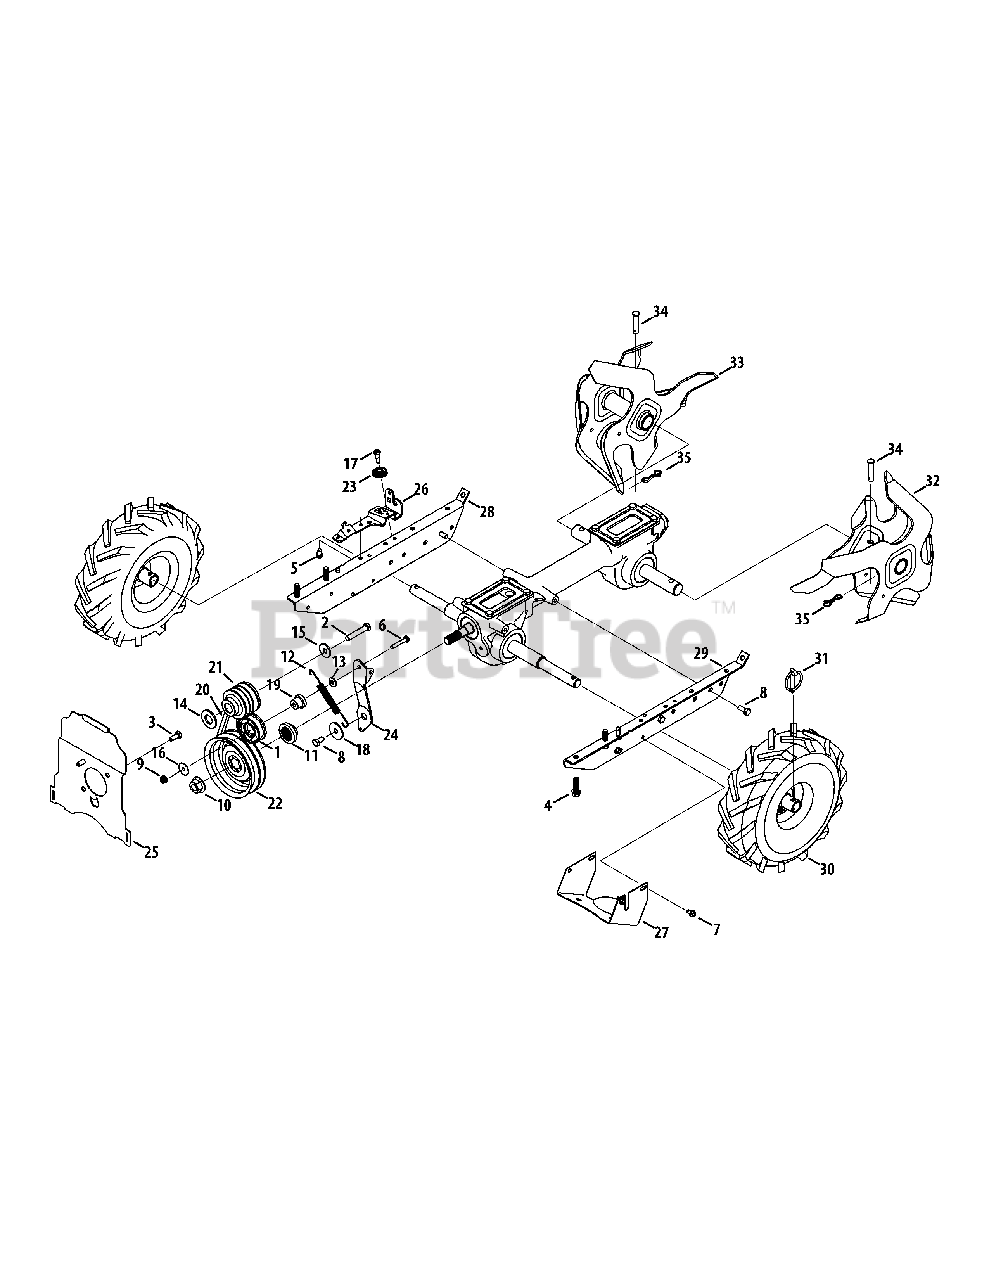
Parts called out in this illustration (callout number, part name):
1	Idler Pulley Assembly
2	Hex Head Screw, 3/8-24 x 2.00
3	Hex Head Screw, 5/16-24 x .625
4	Hex L-Washer TT-Tap, 3/8-16 x 1.25"
5	Self Tapping Screw, 1/4-20 x .500
6	Hex Head Screw, 1/4-20 x 1.50
7	Self Tapping Screw, 1/4-14 x .625
8	Hex Head Screw, 5/16-18 x .75, Patch
9	Nylon Hex Lock Nut, 1/4-20
10	Nut, 9/16-18, Flange Lock
11	Hub, 5/8 Spline
12	Extension Spring, .480 OD X 5.00 LG
13	Washer, .28 x .74 x .063
14	Washer, Flat, .760 x 1.50 x .120
15	Bell Washer, .396 x 1.140 x .095
16	Flat Washer, .265 x 1.0 x .030
17	Shoulder Screw, .342 x .335 1/4-28
18	Pivot Idler Spacer
19	Shoulder Spacer, .260 x .785 x .538
20	V-Belt, 4L x 25.375 Long
21	Engine Pulley
22	Transmission Pulley
23	Cable Roller
24	Idler Bracket, Forward
26	Pulley Bracket
27	Pulley Shield
28	Mounting Frame, RH
29	Mounting Frame, LH
30	Wheel Assembly, 11 x 4 x 4
30	Valve, Tubeless Air
30	Tire, 11 x 4 x 4
32	Tine Assembly, LH
33	Tine Assembly, RH
34	Clevis Pin, .375 x 1.75
35	Cotter Pin, Bow Tie
